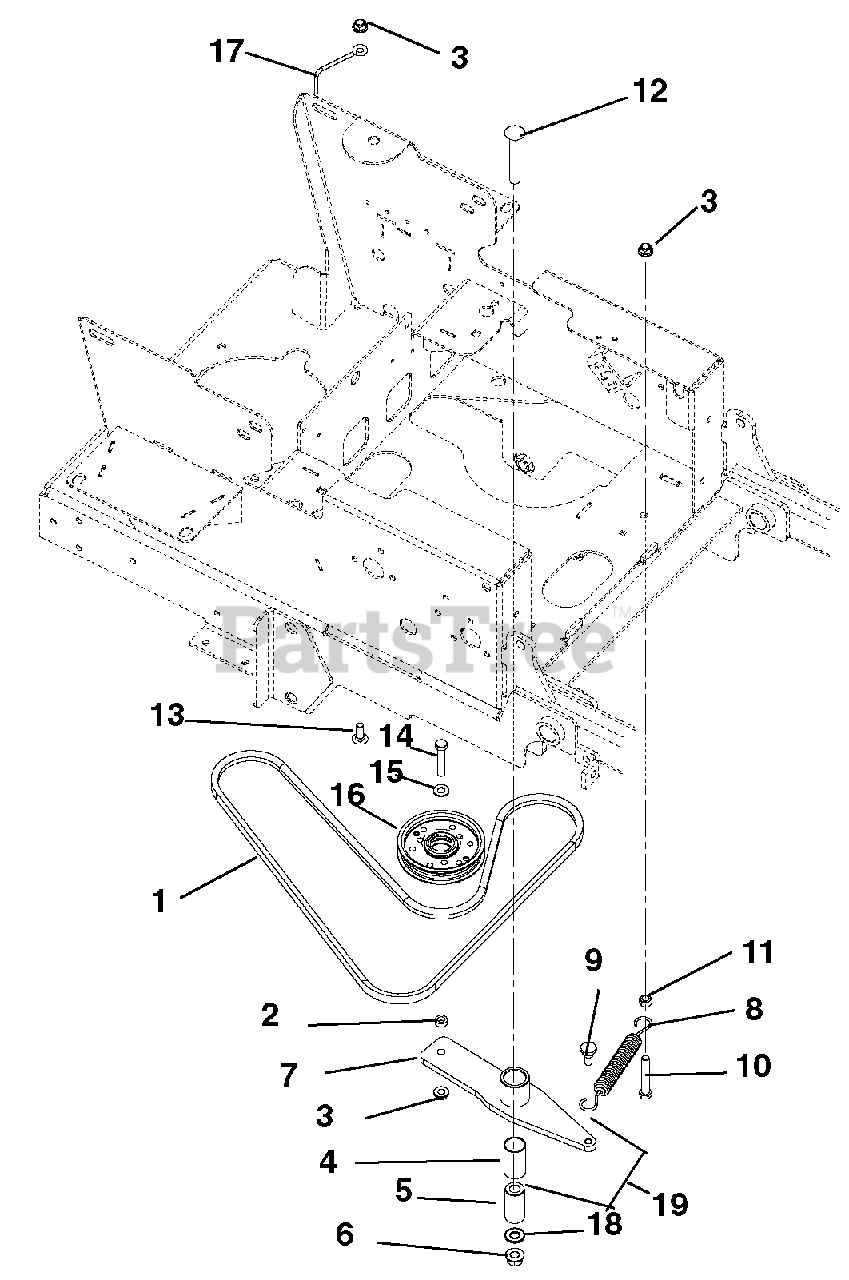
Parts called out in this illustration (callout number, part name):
1	Belt, 4L 67.47 Wrapped
2	Bushing, Sleeve .377 x .624 x .235
3	Nut, .38-16 Nyloc Flange
4	Bushing, 1.00 x 1.125 x 1.936
5	Bushing, Spacer .502 x .997 x 2.03
6	Nut .50-13 Nyloc Flange
7	Weldment, Hydro Drive Idler Arm
8	Spring, Extension
9	Bolt, Shoulder EP .38-16 x .30 Hex
10	Bolt, Hex .38-16 x 2.50 Grade 5
11	Nut, Locking-Center .375-16
12	Bolt, Hex .50-13 x 3.25 Grade 5
13	Bolt, Round Head Square Neck .38-16 x 1.00 Grade 5
14	Bolt, Hex .38-16 x 2.00 Grade 5
15	Washer, Flat-Steel .406 x .812 x .065
16	Assembly, 4" Idler
17	Belt Finger
18	Washer, Flat-STL.511 x 1.441 x .125
19	Assembly, Idler Pivot Arm
